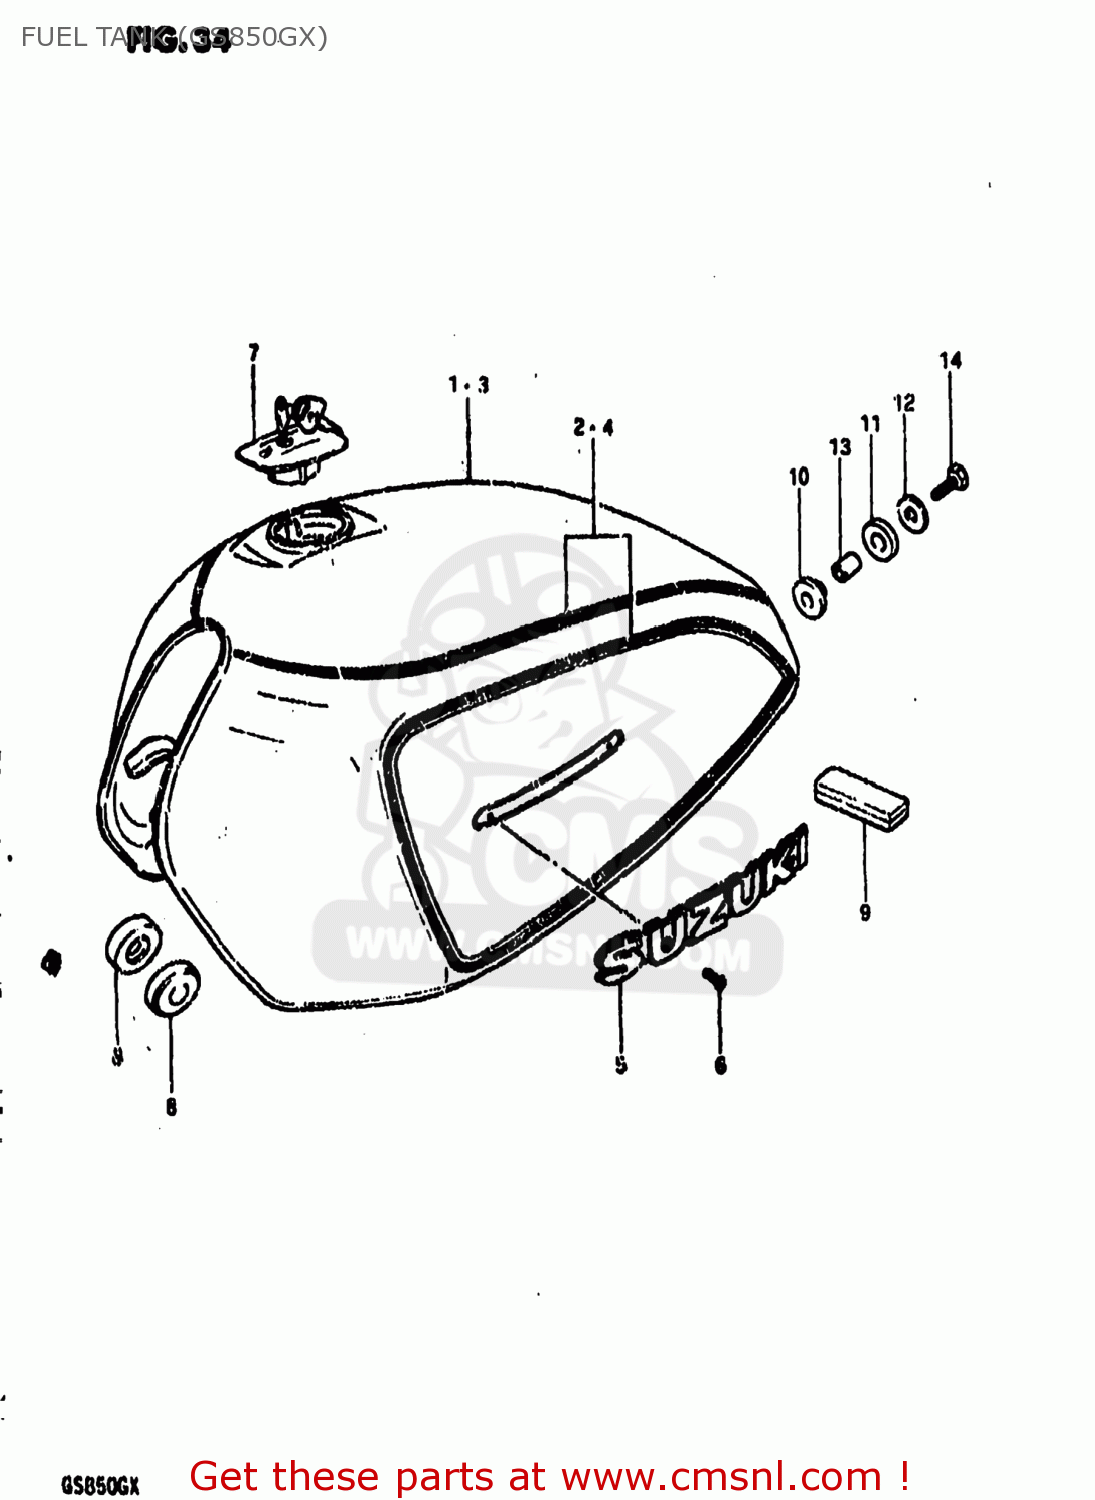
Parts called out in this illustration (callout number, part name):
1	TANK ASSEMBLY,FUEL
2	TAPE SET,FUEL TANK
3	TANK ASSEMBLY,FUEL
4	TAPE SET,FUEL TANK
5	EMBLEM,FUEL TANK
6	SCREW 3X6
7	CAP SET,FUEL TANK
8	CUSHION
9	CUSHION
10	CUSHION
11	CUSHION
12	WASHER (8.5X29X1.6)
13	SPACER(8.5X12X19)
14	BOLT (8X30)
